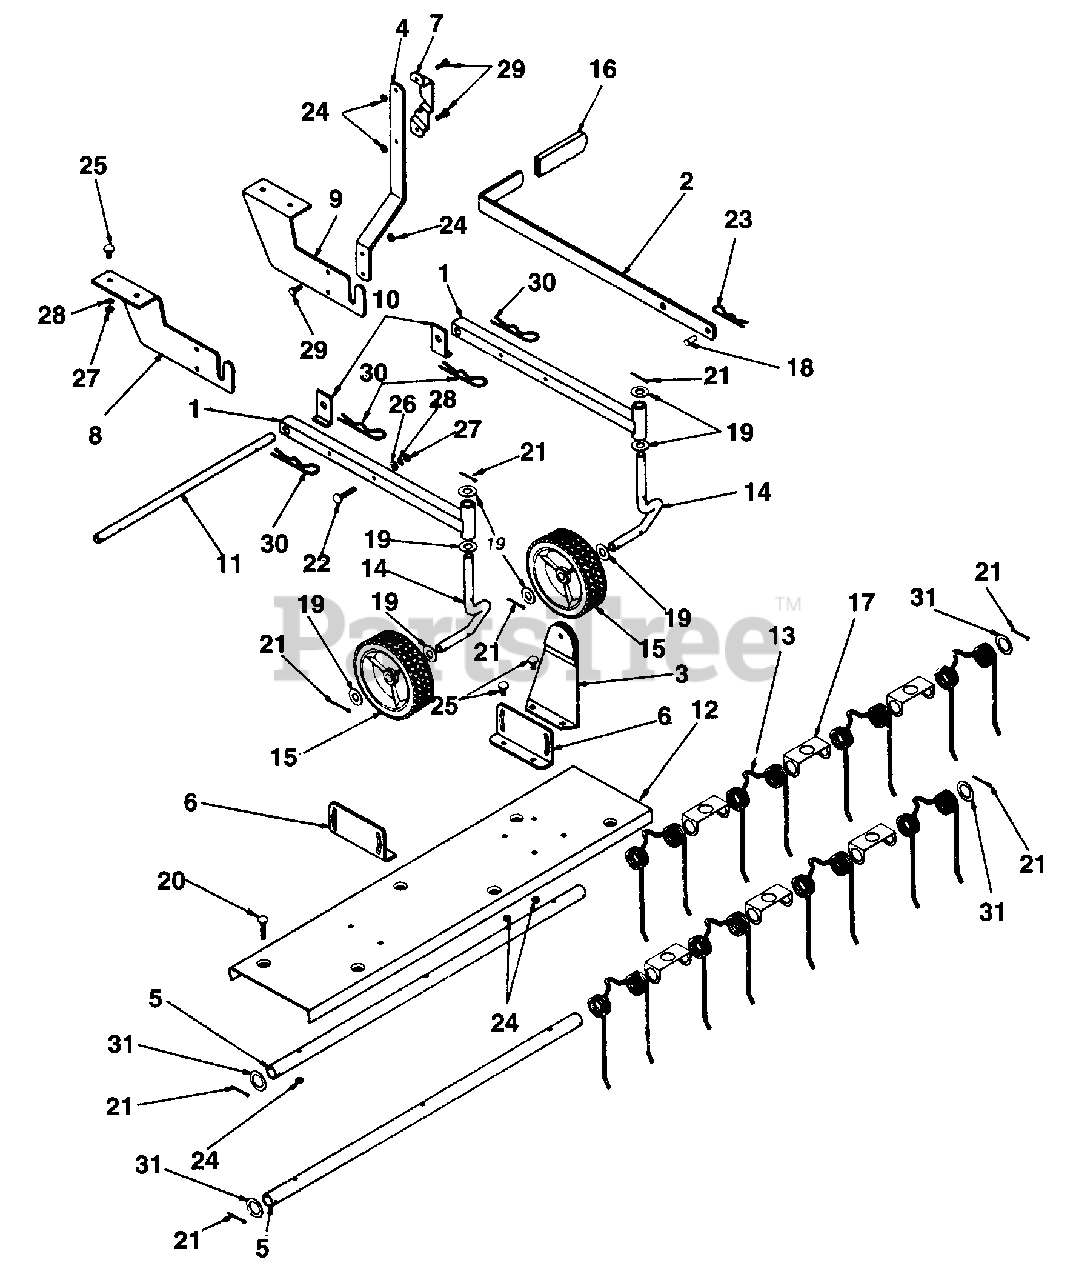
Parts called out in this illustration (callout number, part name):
1	Arm, Mounting
2	Handle, Lift
3	Bracket, Lift Handle
4	Arm, Lift Handle
5	Tube, Spring Mounting
6	Bracket, Angle Mounting
7	Bracket, Handle Lock
8	Bracket, R.H.--Hitch
9	Bracket, L.H.--Hitch
10	Keeper, Plate
11	Shaft, Mounting
12	Shield, Spring Mounting
13	Spring, De-Thatcher
15	Wheel, Cream
16	Grip, Lift Handle
17	Bracket, Spring
18	Pin, Clevis, 3/8" Dia. x .75" Lg.
19	Washer, Pivot
20	Bolt, Carriage, 5/16-18 x 1.50" Lg.
21	Pin, Cotter, 1/8" Dia. x 1.00" Lg.
22	Bolt, Carriage, 5/16-18 x 1.75" Lg.
23	Pin, Quick Attach
24	Nut, Hex Center Lock, 5/16-18
25	Bolt, Carriage, 5/16-18 x .75" Lg.
26	Washer, Flat
27	Nut, Hex, 5/16-18
28	Washer, Lock, 5/16
29	Screw, Hex Cap, 5/16-18 x .75" Lg. (Gr. 5)
30	Cotter, Hairpin
31	Washer, Flat
